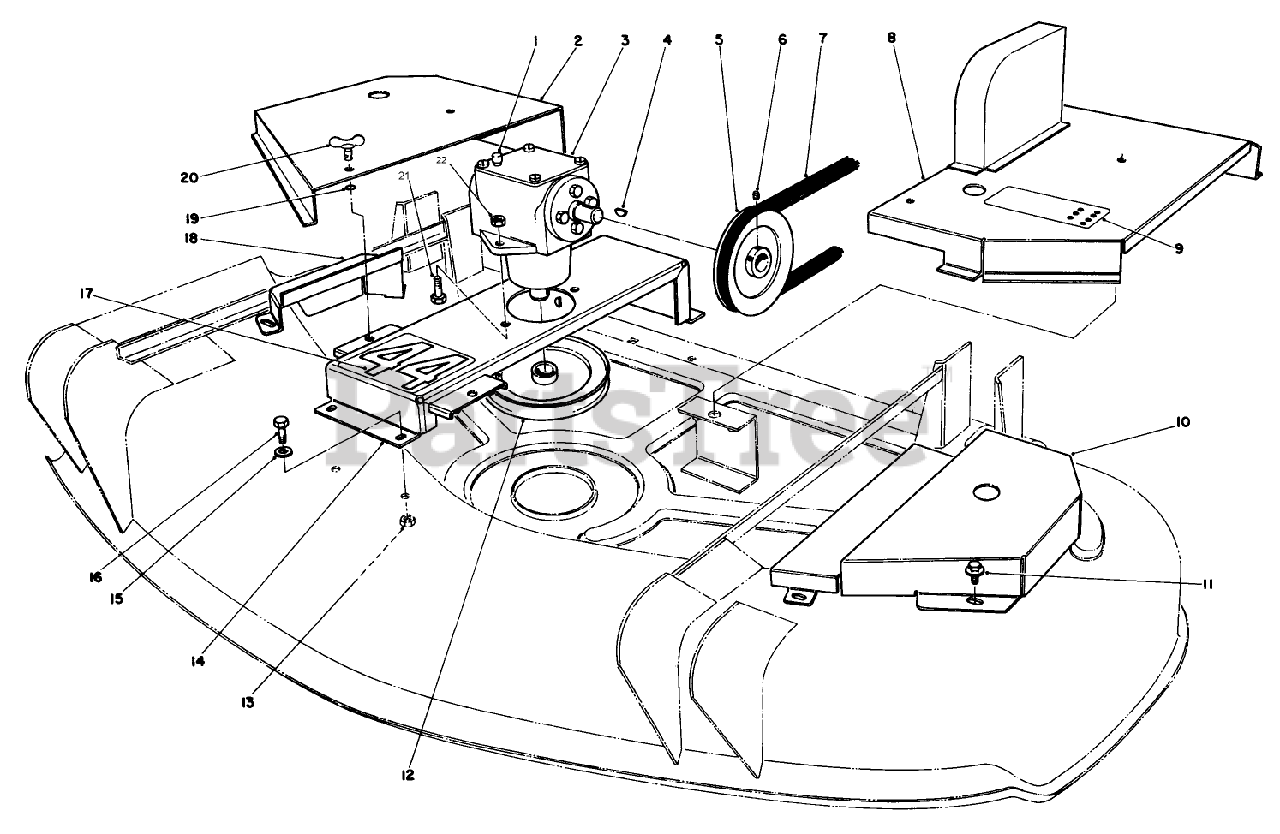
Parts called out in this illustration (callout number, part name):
4	KEY-WOODRUFF
6	SCREW-SET
7	V-BELT-DRIVE, DECK
11	SCREW-HHFTF
13	NUT-LOCK, CONE
15	WASHER-PLAIN
16	SCREW-HH
17	DECAL-44 INCH
19	RING-RETAINING
20	STUD-HEAD, WING
21	SCREW-HH
22	NUT-LOCK, CONE
